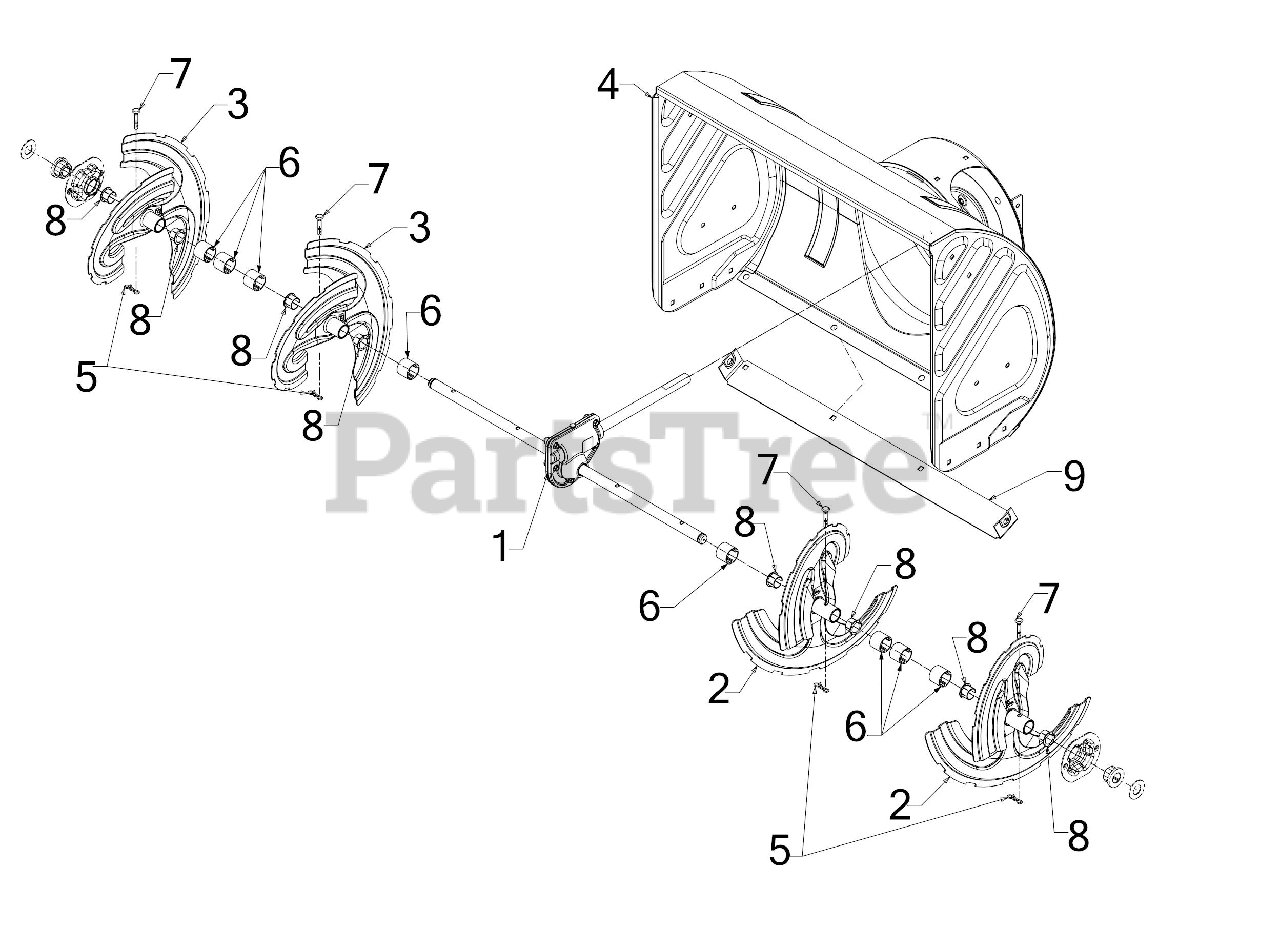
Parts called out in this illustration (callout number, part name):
1	28" GEARBOX ASSEMBLY
5	BOW TIE COTTER PIN 1/4-5/16
6	SPACER 1.25OD x .75ID X1.00 LG
7	SHEAR PIN .25 x 1.50 GR2
8	FLANGE BUSHING
